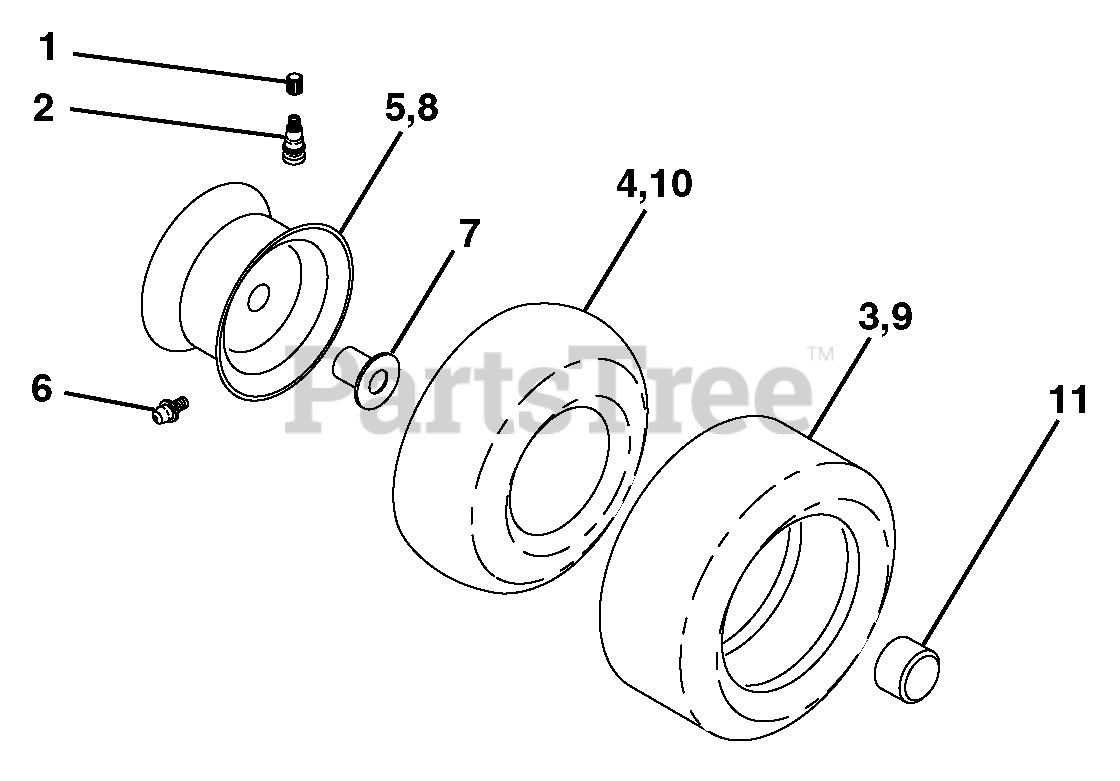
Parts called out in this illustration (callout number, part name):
1	Cap Valve Tire
2	Stem Valve
3	Tire F Ts 15 x 6 0 - 6 Service
4	Tube Front
5	Rim Asm 6" Front Service
6	Fitting Grease
7	Bearing Flange
8	Rim Asm 8" Rear Service
9	Tire R Ts 18 x 8.5-8 Service
10	Tube Rear
11	Cap Axle 1 50 x 1 00
